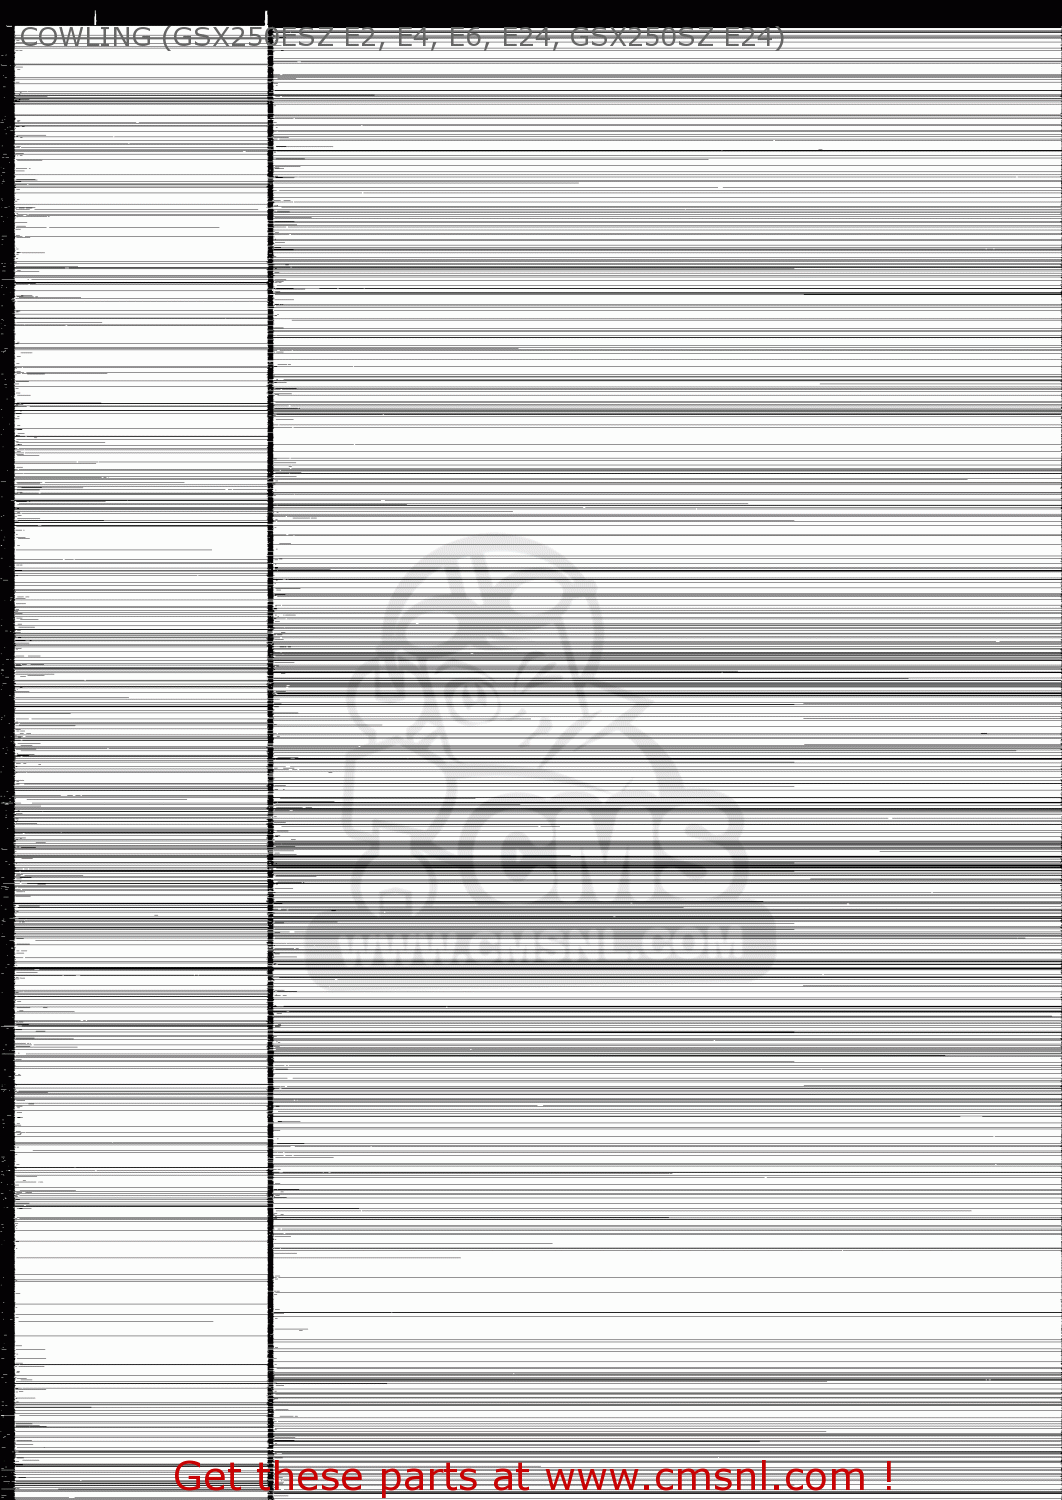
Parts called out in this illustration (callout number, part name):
1	COWLING ASSY (RED)
2	COWLING ASSY
3	WINDOW
4	MOULDING
5	CUSHION
6	SCREW
7	WASHER
8	NUT
9	BRACKET,COWLING RH
10	BRACKET,COWLING LH
11	BOLT
12	LOCK WASHER
13	BRACKET, FITTING RH
14	BRACKET, FITTING LH
15	BOLT, UPPER
16	WASHER (6.5X18X1.6)
17	BRACKET, LOWER
18	BOLT
19	LOCK WASHER
20	WASHER
21	MOLDING,HEADLAMP GRILL
